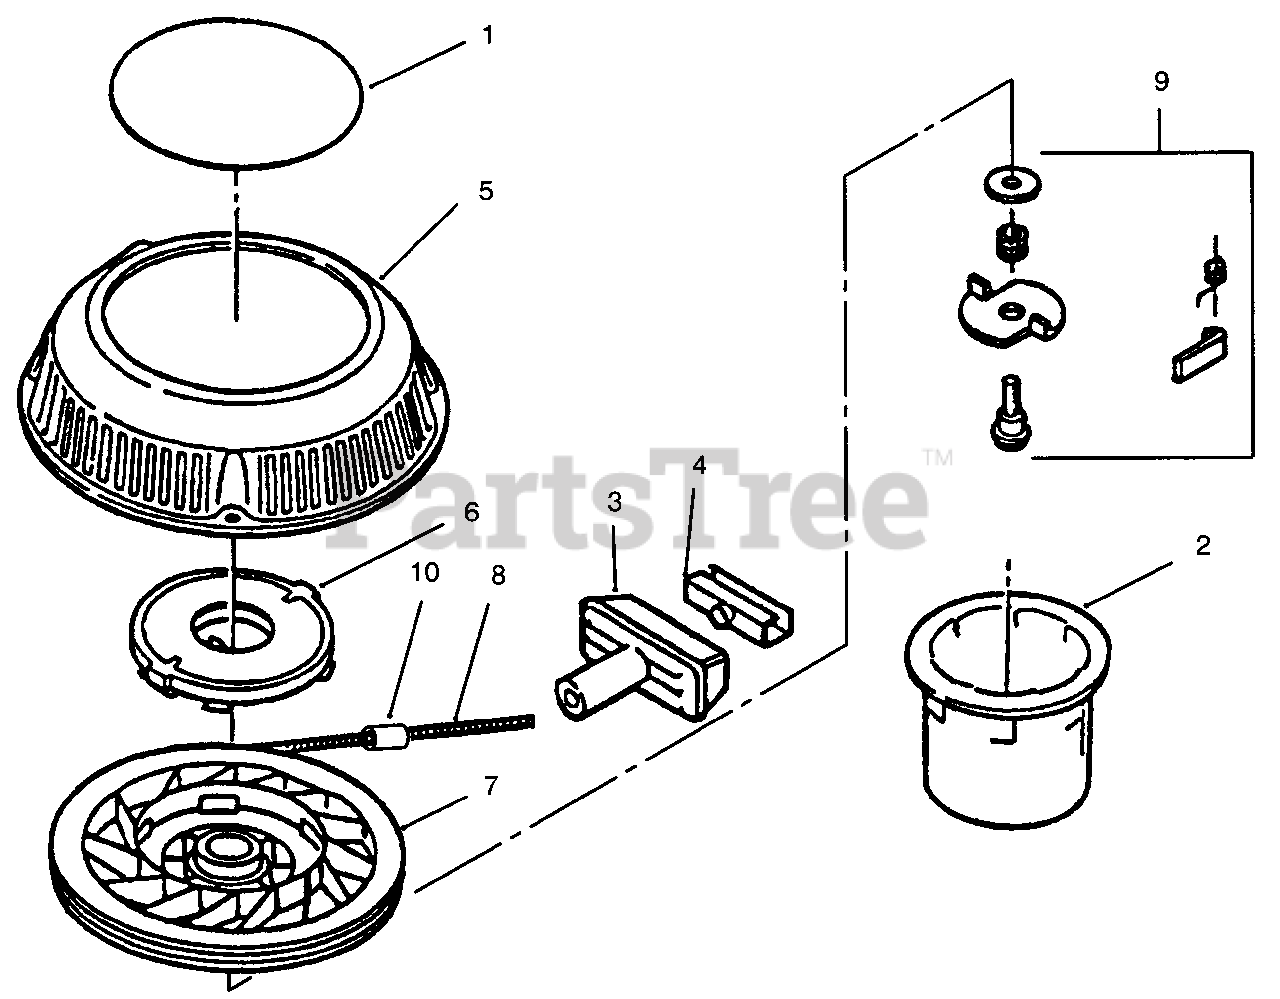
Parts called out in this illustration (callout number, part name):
1	Decal-Recoil
2	Hub-Starter
3	Handle-Starter
4	Insert-Clip,Rope
5	Housing-Starter
6	Recoil Spring & Keeper
8	Rope
9	Assembly-Dog Kit
10	Stop-Rope
